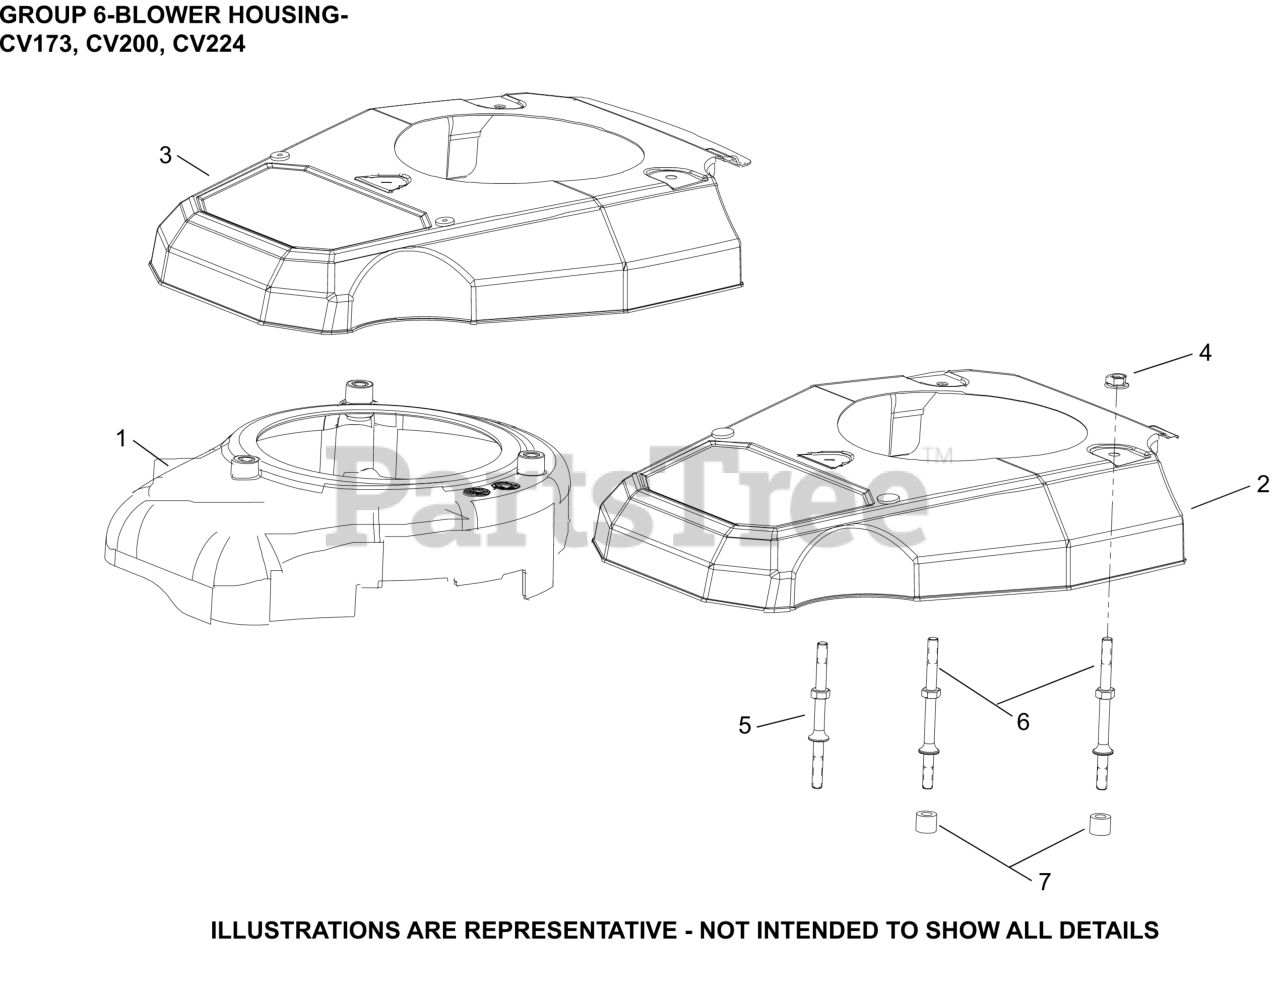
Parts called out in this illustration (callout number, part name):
1	KIT, BLOWER HOUSING
3	COVER, ENGINE
4	NUT, HEX FLANGE (M6) - USE 14 100 16-S
5	STUD-USE 14 072 25-S
6	STUD, BLOWER HOUSING
